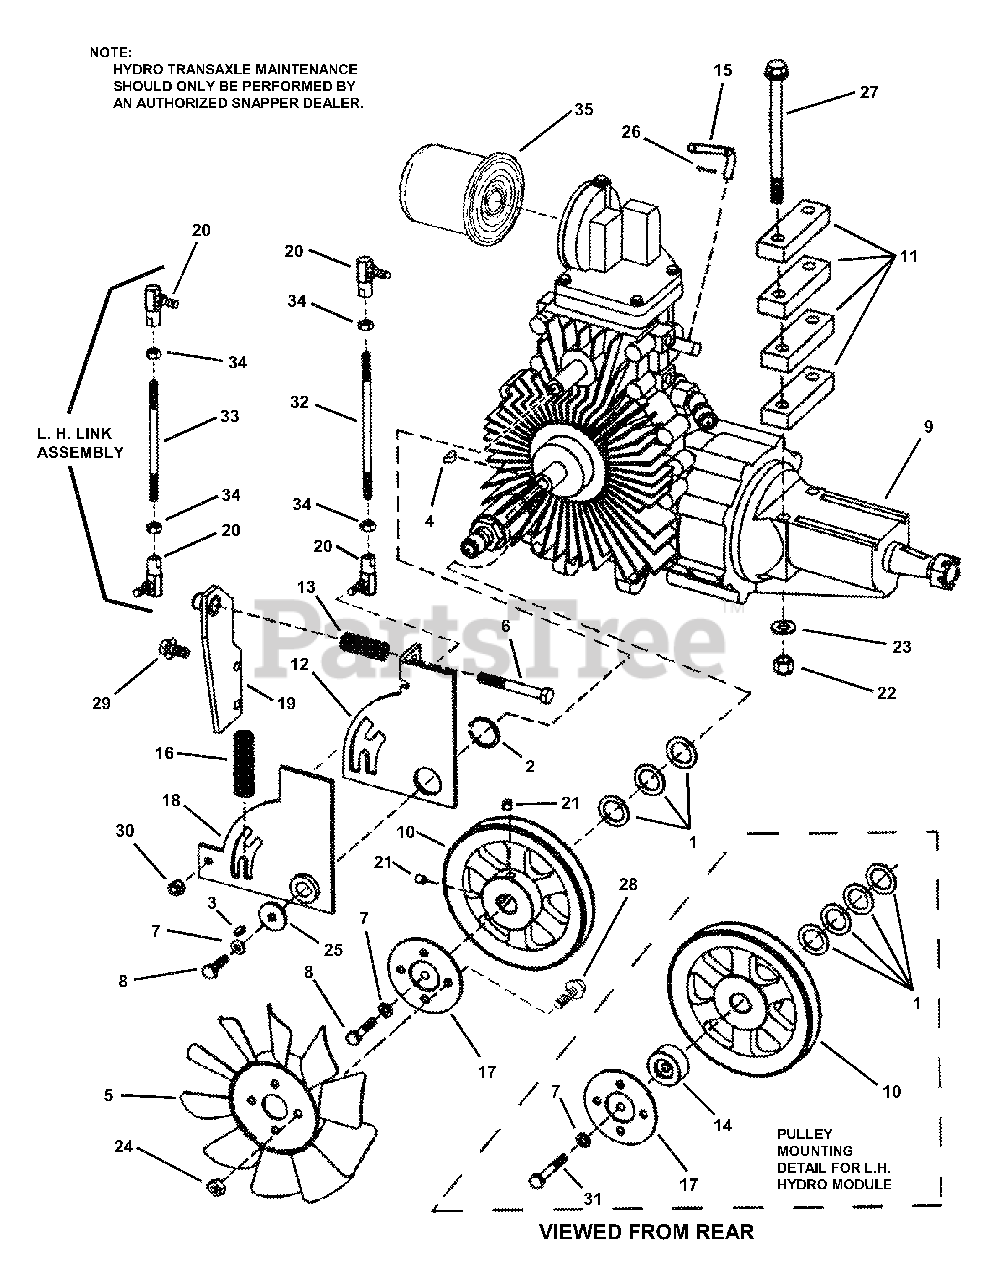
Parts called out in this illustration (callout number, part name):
1	WASHER, 3/4 I.D. x 1-1/8" O.D. Flat
2	RETAINING RING, 1" External
3	WOODRUFF KEY, #404
4	WOODRUFF KEY, #605
5	FAN, 10 Blade 7" Dia.
6	BOLT, 5/16-18 X 2-1/2" GD5 YZ
7	WASHER, 1/4 Split Lock
8	SCREW, 1/4-20 x 1-1/4", Hex Head Cap
9	ASSEMBLY, Transaxle 771-108 (R.H.)
10	PULLEY, Transmission Input
11	SPACER, Eaton Transaxle
12	PLATE, Neutral Adjust
13	SPRING, Neutral Return Adjust
14	SPACER/ADAPTER, Fan
15	ROD, Roll Release
16	SPRING, Neutral Return
17	SPACER, Fan (Weldment)
18	CAM, Neutral Return (Weldment)
19	PLATE, Neutral Return
20	BALL-JOINT
21	SET SCREW, 5/16-18 x 5/16" Hex Recess
22	NUT, 3/8-16 HEX NYLON LOCK
23	WASHER, 3/8 SAE Flat
24	NUT, 1/4-20 HEX NYLON LOCK
25	WASHER, 1/4 I.D. x 1" O.D.
26	COTTER-PIN, 1/16 x 1/2"
27	BOLT, 3/8-16 x 4-3/4" Grade 5
28	SCREW, 1/4-20 x 5/8" Hex Flange Lock, Grade 5
29	BOLT, 5/16-18 x 5/8", Hex Flange Lock
30	NUT, 1/4-28, Hex Nyloc
31	SCREW, 1/4-20 x 2", Hex Head Cap, Grade 5
32	ROD, Threaded 1/4-28 x 5-3/8"
33	ROD, Threaded 1/4-28 x 4-3/8"
34	HN, 1/4F GR5 YZ
35	FILTER, Oil (EATON No. 103144)
